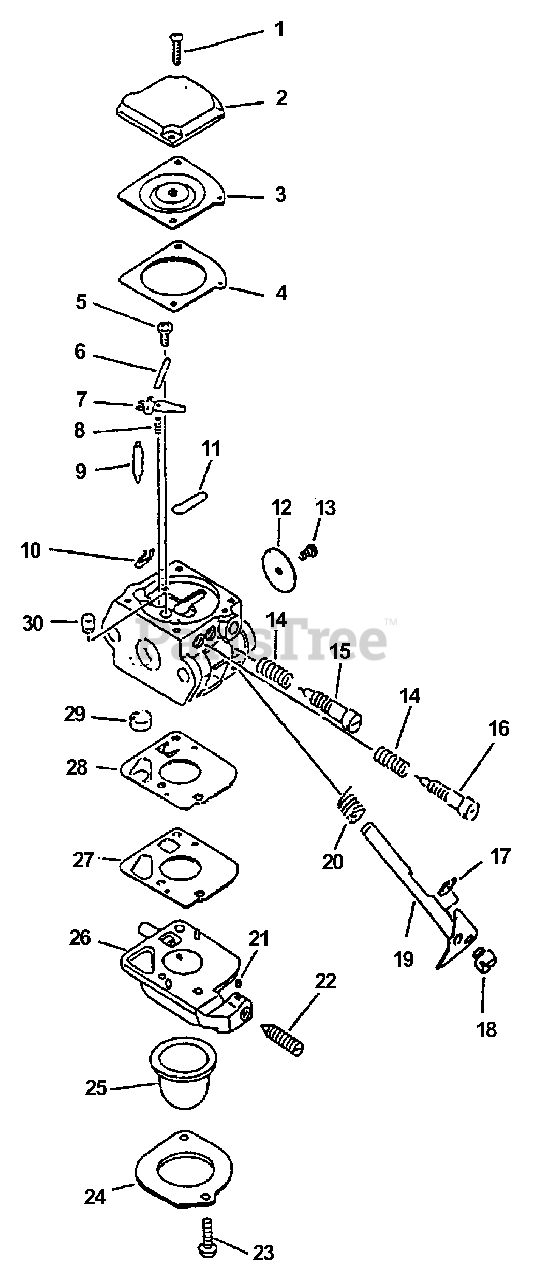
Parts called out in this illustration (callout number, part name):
2	COVER, DIAPHRAGM
3	DIAPHRAGM, METERING
4	GASKET, METERING
5	SCREW, METERING LEVER PIN
6	PIN, METERING LEVER
7	LEVER, METERING
8	SPRING, METERING LEVER
9	VALVE, INLET NEEDLE
11	PLUG, WELCH
12	VALVE, THROTTLE
14	SPRING, NEEDLE
15	NEEDLE, LOW SPEED
16	NEEDLE, HIGH SPEED
19	SHAFT, THROTTLE
20	SPRING, THROTTLE RETURN
21	PIECE, FRICTION
22	SCREW, IDLE ADJUST
24	RETAINER
25	BULB, PURGE
26	BODY ASSY, PURGE
29	STRAINER
30	NOZZLE, CHECK VALVE
